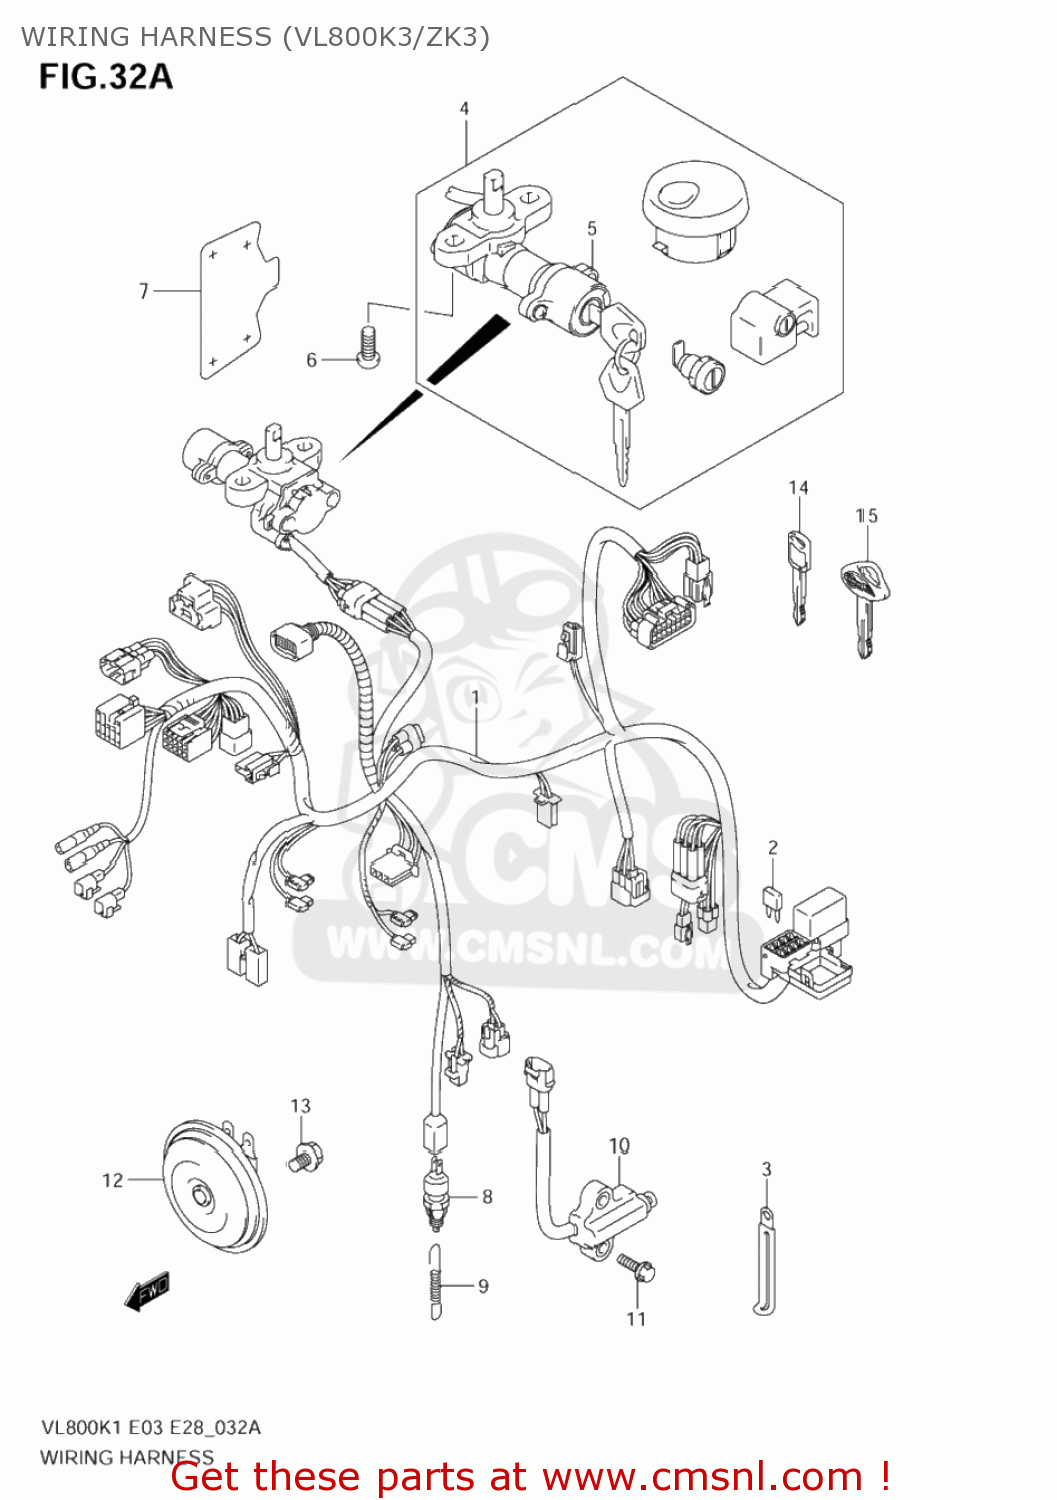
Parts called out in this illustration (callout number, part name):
1	HARNESS,WIRING
2	FUSE(10A)
3	CLAMP(L:80)
4	LOCK SET
5	LOCK ASSY,STEERING
6	BOLT(8X20)
7	PROTECTOR,IGNITION SWITCH
8	SWITCH ASSY,STOP LAMP
9	SPRING
10	SWITCH ASSY,SIDE STAND
11	BOLT
12	HORN ASSY
13	BOLT
14	KEY,BLANK
15	KEY,BLANK(VOLUSIA)
